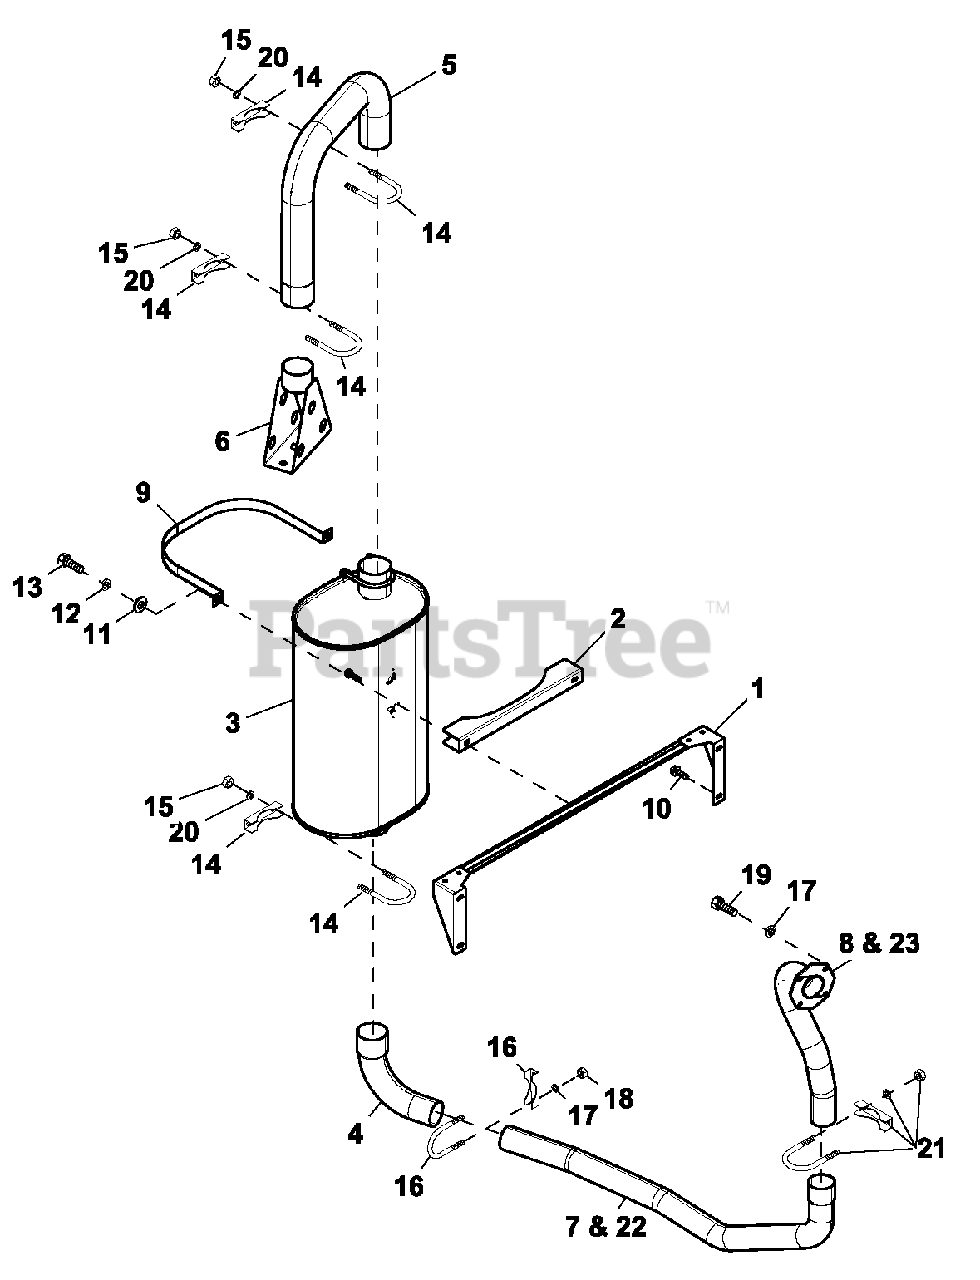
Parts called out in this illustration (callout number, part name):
1	BRACKET MUFFLER
2	BRACKET STIFFENER
3	MUFFLER 60kW
4	EXHAUST ELBOW
5	EXHAUST PI PE
6	DIFFUSER EXHAUST WELDMENT
7	PI P E EXHAUST 2.4L 60kW
8	U P P ER EXHAUST PI P E ASM
9	STRAP MUFFLER
10	SCREW THFM6-1 X 16 N WA Z/JS
11	WASHER FLAT 1/4-M6 ZINC
12	WASHER LOCK M6-1/4
13	SCREW HHC M6-1.0 X 35 G8.8 BLK
14	BOLT U 3 /8 -1 6 X 2 .6 2
15	NUT HEX 3/8-16 STEEL
16	BOLT U 5 /1 6 -1 8 X 2 .2 5
17	WASHER LOCK M8 SS
18	NUT HEX 5/16-18 STEEL
19	SCREW HHC M8-1.25 X 20 SS
20	WASHER LOCK 3/8
21	BOLT U 3/8-16 X 2.30 W/SADDLE
22	EXHAUST BLANKET 600MM LONG
23	EXHAUST BLANKET 737MM
